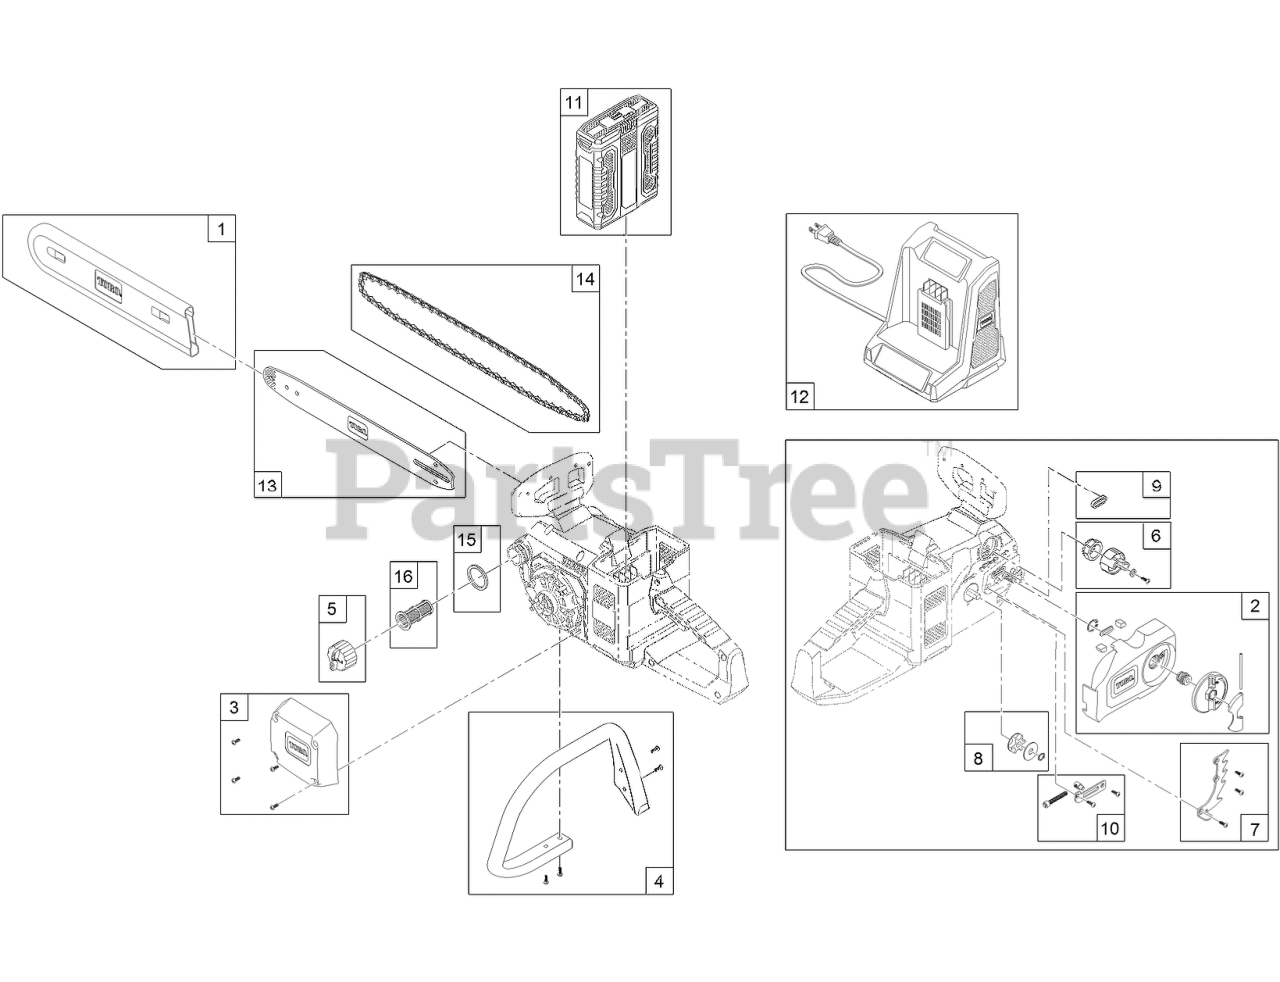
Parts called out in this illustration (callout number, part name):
1	SLEEVE-BAR/CHAIN
2	CHAIN BAR PANEL ASM
3	COVER-MOTOR
4	HANDLE
5	CAP-OIL, BAR
6	ADJUSTER KNOB WITH BAR AND CHAIN ASM
7	BUCKING TEETH BRACKET ASM
8	SPROCKET-DRIVE, CHAIN
9	GASKET-OIL, BAR/HOUSING
10	ADJUSTER BAR WITH PIN AND SCREW ASM
11	BATTERY-40V MAX
12	CHARGER-40V MAX
13	Bar-REPLACEMENT
14	CHAIN-REPLACEMENT
15	GASKET-OIL CAP, BAR
16	STRAINER-OIL, BAR
